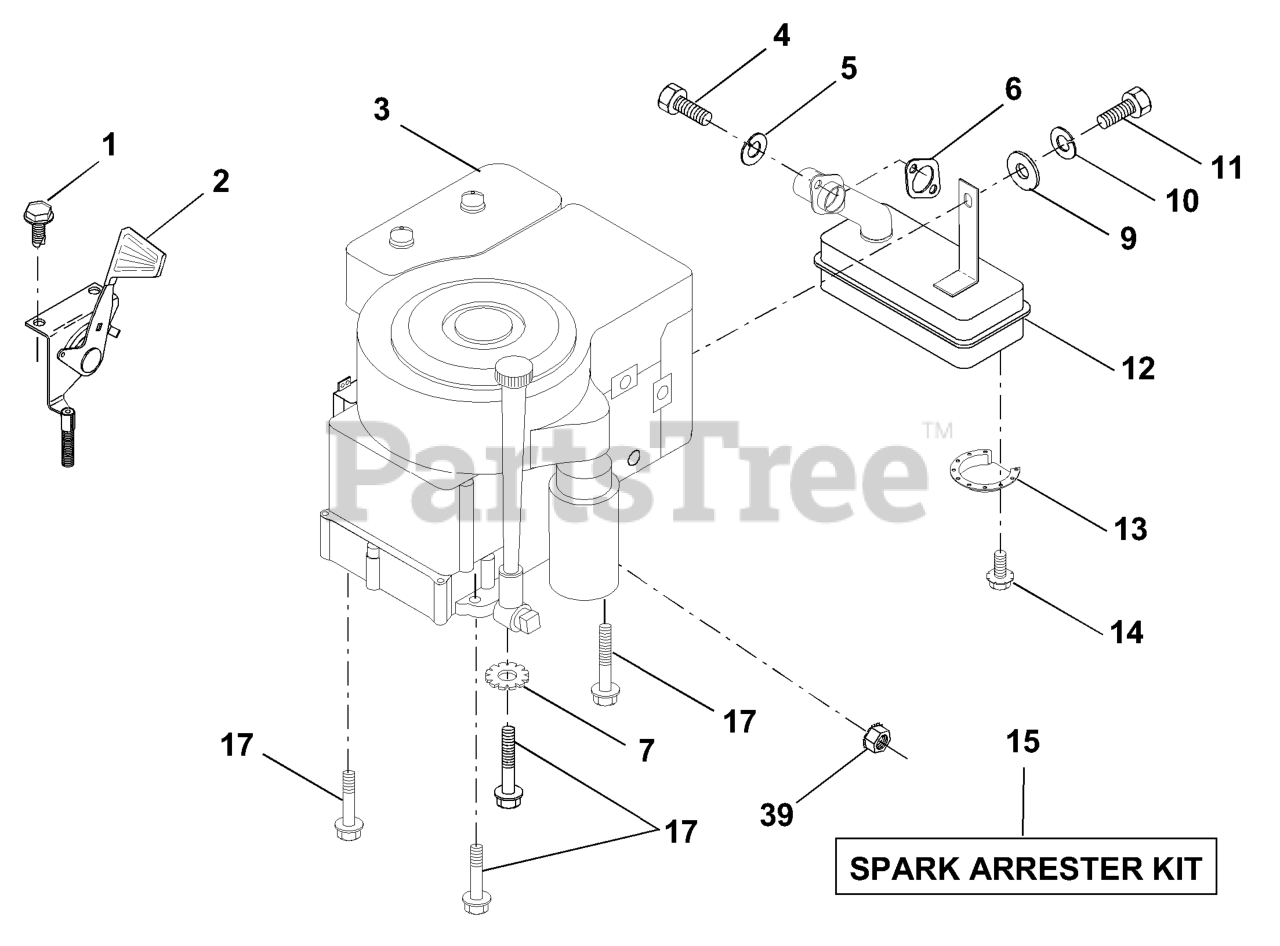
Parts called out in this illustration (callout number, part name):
2	CONTROL.TH/CH.RH.BLK.FLG.26
3	Engine, Briggs and Stratton Model No. 283707
4	SCREW
5	WASHER.LOCK.HVY.HLCL.SPR.5/16
6	GASKET.ENG.1.313 ID.TIN PLATED
7	LOCKWASHER
9	WASHER
10	LOCKWASHER
11	Bolt, Hex Fin.
12	MUFFLER.SINGLE.B&S.12HP
13	DEFL MUFFLER LTV
14	SCREW
15	KIT.SPARK ARRESTOR 794945 B&S
17	SCREW LT
39	NUT FLANGE 1/4-20 STARTER NUT
